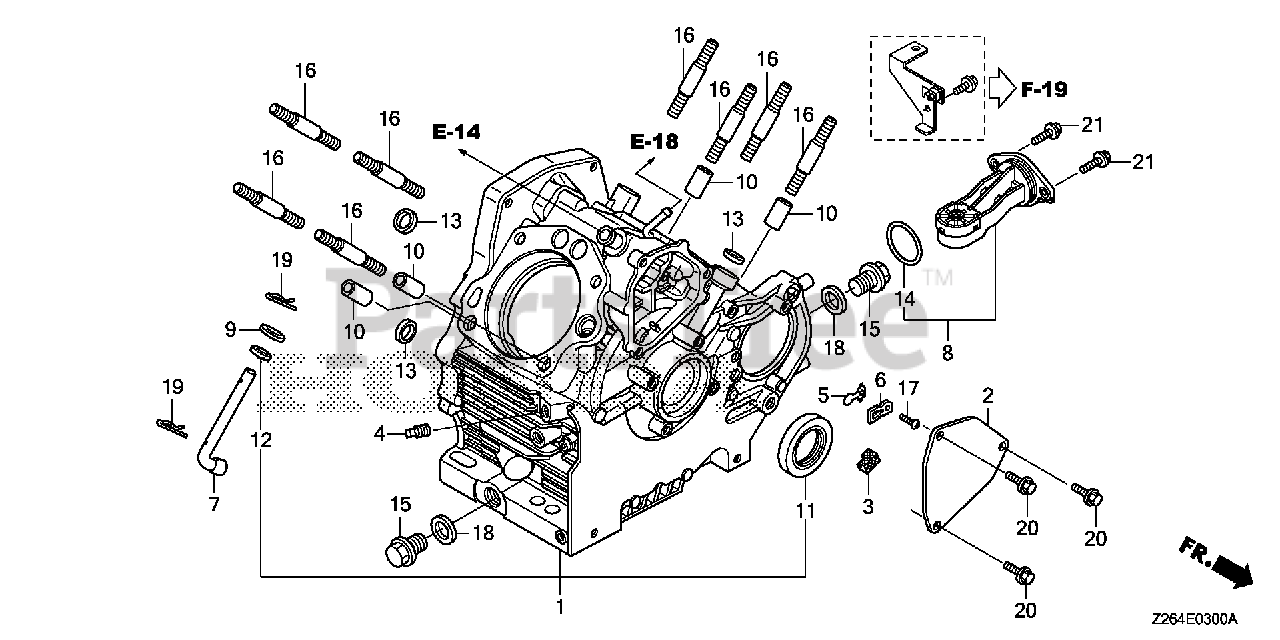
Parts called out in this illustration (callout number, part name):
1	CRANKCASE ASSY.
2	COVER, BREATHER
3	FILTER, BREATHER
4	BOLT, SEALING
5	VALVE, OIL OUTLET
6	PLATE, STOPPER
7	SHAFT, GOVERNOR ARM
8	SWITCH ASSY., OIL LEVEL
9	WASHER, PLAIN (10MM)
10	PIN, DOWEL (12X20)
11	OIL SEAL (38X58X9)
12	OIL SEAL (10X16X5)
13	GASKET, OIL PASSAGE
14	O-RING (37.9X2.4)
15	BOLT, DRAIN PLUG (20MM)
16	BOLT, STUD (10X40)
17	SCREW, PAN (3X8)
18	WASHER, DRAIN PLUG (20MM)
19	PIN, LOCK (10MM)
20	BOLT, FLANGE (6X14)
21	BOLT, FLANGE (6X16)
